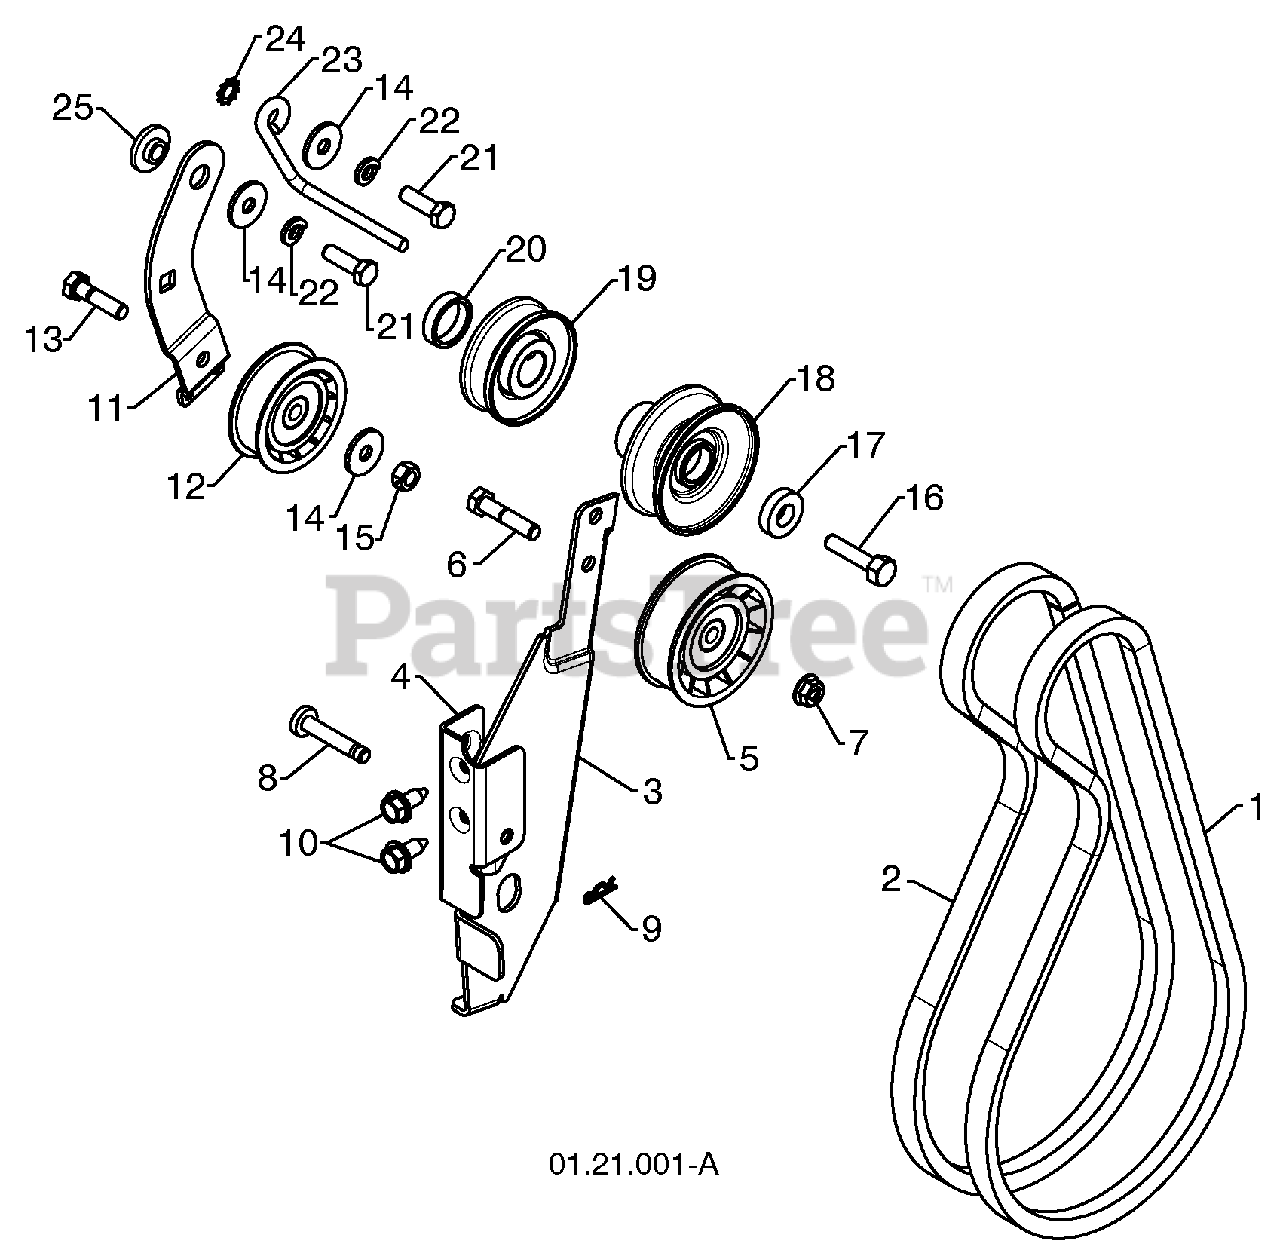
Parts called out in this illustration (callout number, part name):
1	IMPELLER BELT
2	TRACTION BELT
3	IDLER ARM
4	IDLER BRACKET
5	IDLER PULLEY
6	SCREW 5/16-18 X 1.50
7	NUT 5/16-18
8	IDLER ARM PIN
9	RETAINER CLIP
10	SCREW 5/16-18 X .625
11	TRACTION IDLER ARM
12	TRACTION PULLEY
13	SCREW 5/16-18 X 1.00
14	WASHER
15	NUT 5/16-18
16	IDLER BUSHING
17	WASHER
18	ENGINE PULLEY
19	ENGINE TRACTION PULLEY
20	SPACER
21	SCREW 5/16-18 X 1.00
22	LOCKWASHER 5/16
23	BELT GUIDE
24	LOCKWASHER 5/16
25	IDLER BUSHING
